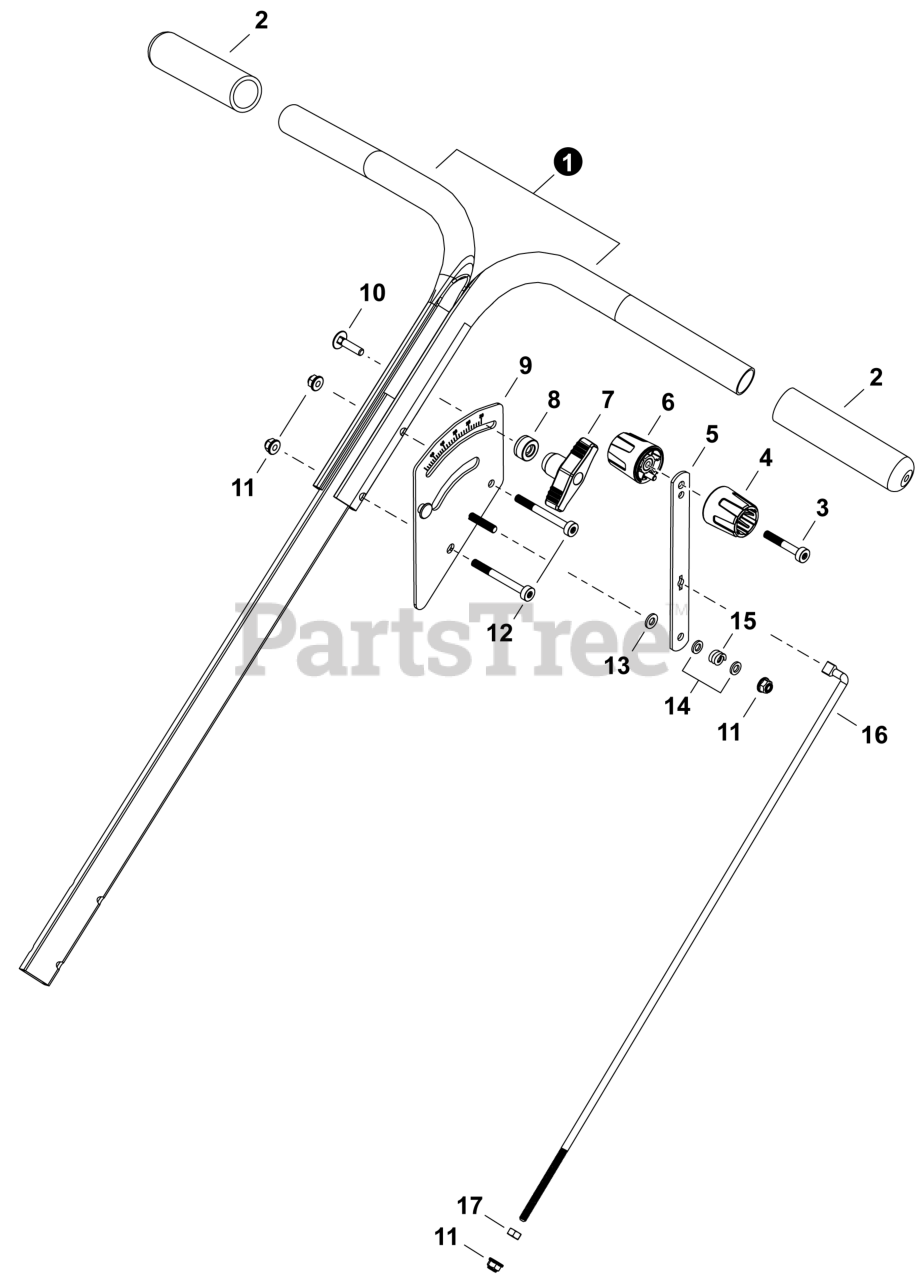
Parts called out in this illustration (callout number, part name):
2	GRIP, HANDLE
3	BOLT 6x40
4	KNOB, REGULATOR - LEFT
5	LEVER, REGULATOR
6	KNOB, REGULATOR - RIGHT
7	THUMBSCREW
9	BRACKET, REGULATOR
10	BOLT M6 x 26MM
12	BOLT, M6 X 60MM
14	WASHER 6
15	SPRING, COMPRESSION
16	ROD, REGULATOR
17	NUT, HEX M6
